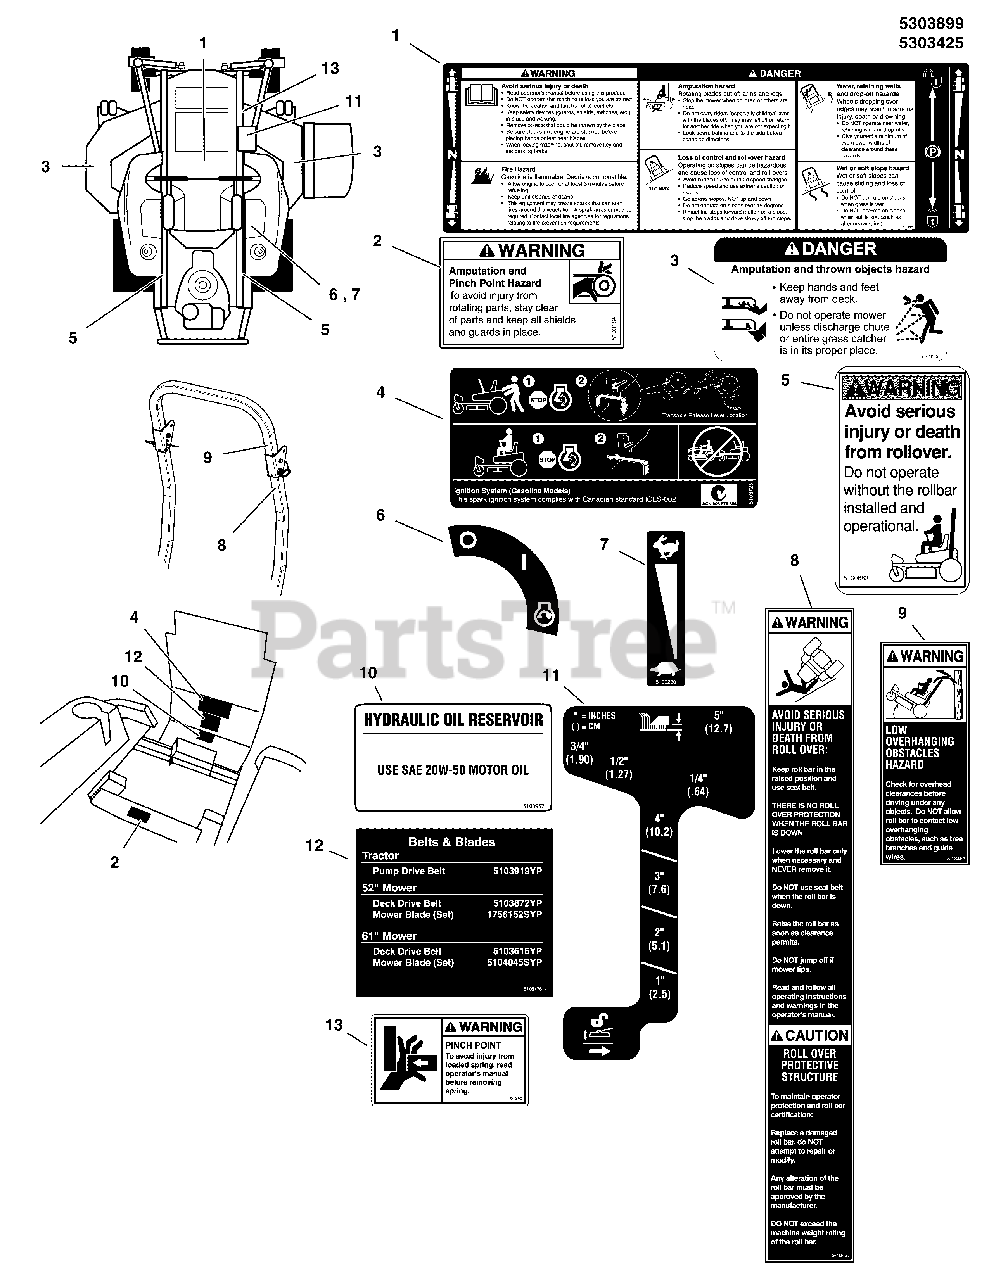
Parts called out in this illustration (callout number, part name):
1	DECAL, MAIN SAFETY
2	DECAL, WARNING, HAND IN BELT, ENG ONLY
3	DECAL, DANGER DO NOT OPERATE W/O DEFLECT
4	DECAL, TRANSAXLE RELEASE, 600/700
5	DECAL, WARNING, ROLL BAR
6	DECAL, IGNITION SWITCH
7	DECAL, THROTTLE CONTROL
8	DECAL, WARNING & CAUTION, ROPS (SV)
9	DECAL, WARNING OVERHANG, ROPS (SV)
10	DECAL, HYDRAULIC OIL, 20W50
11	DECAL, CUT HEIGHT, IS700/ZTS700
12	DECAL, BELT & BLADE, 560/CONTENDER
13	DECAL, PINCH POINT
